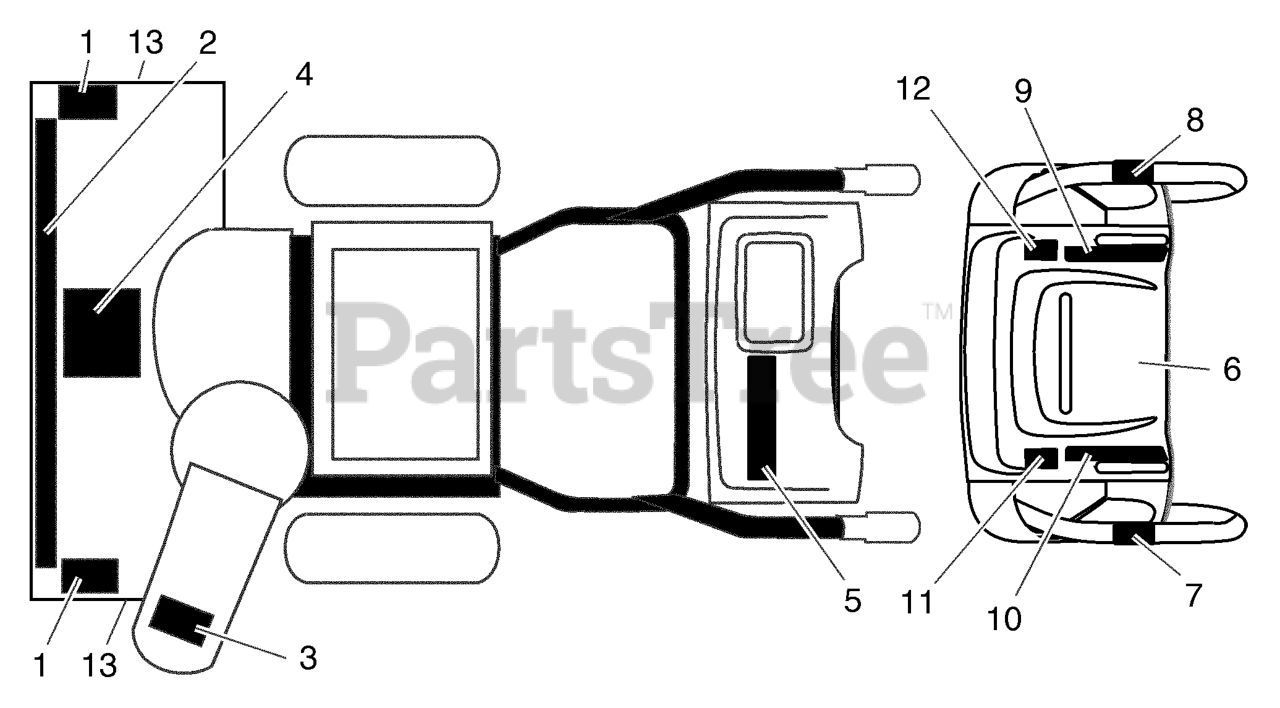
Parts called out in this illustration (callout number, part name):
1	DECAL DANGER
2	DECAL, HUSQVARNA
3	DECAL, DANGER DEFLECTOR
4	DECAL, DANGER
5	DECAL, HUSQVARNA 1130ST
6	DECAL.SNOWTHROWER.CONSOLE.INST
7	DECAL.TRACT.ASM.ENG.CLUTCH.K
8	DECAL, AUGER LEVER
9	DECAL, SPEED CONTROL
10	DECAL, REMOTE DEFLECTOR
11	DECAL, LH TRIGGER
12	DECAL, RH TRIGGER
13	DECAL, HUSQVARNA
